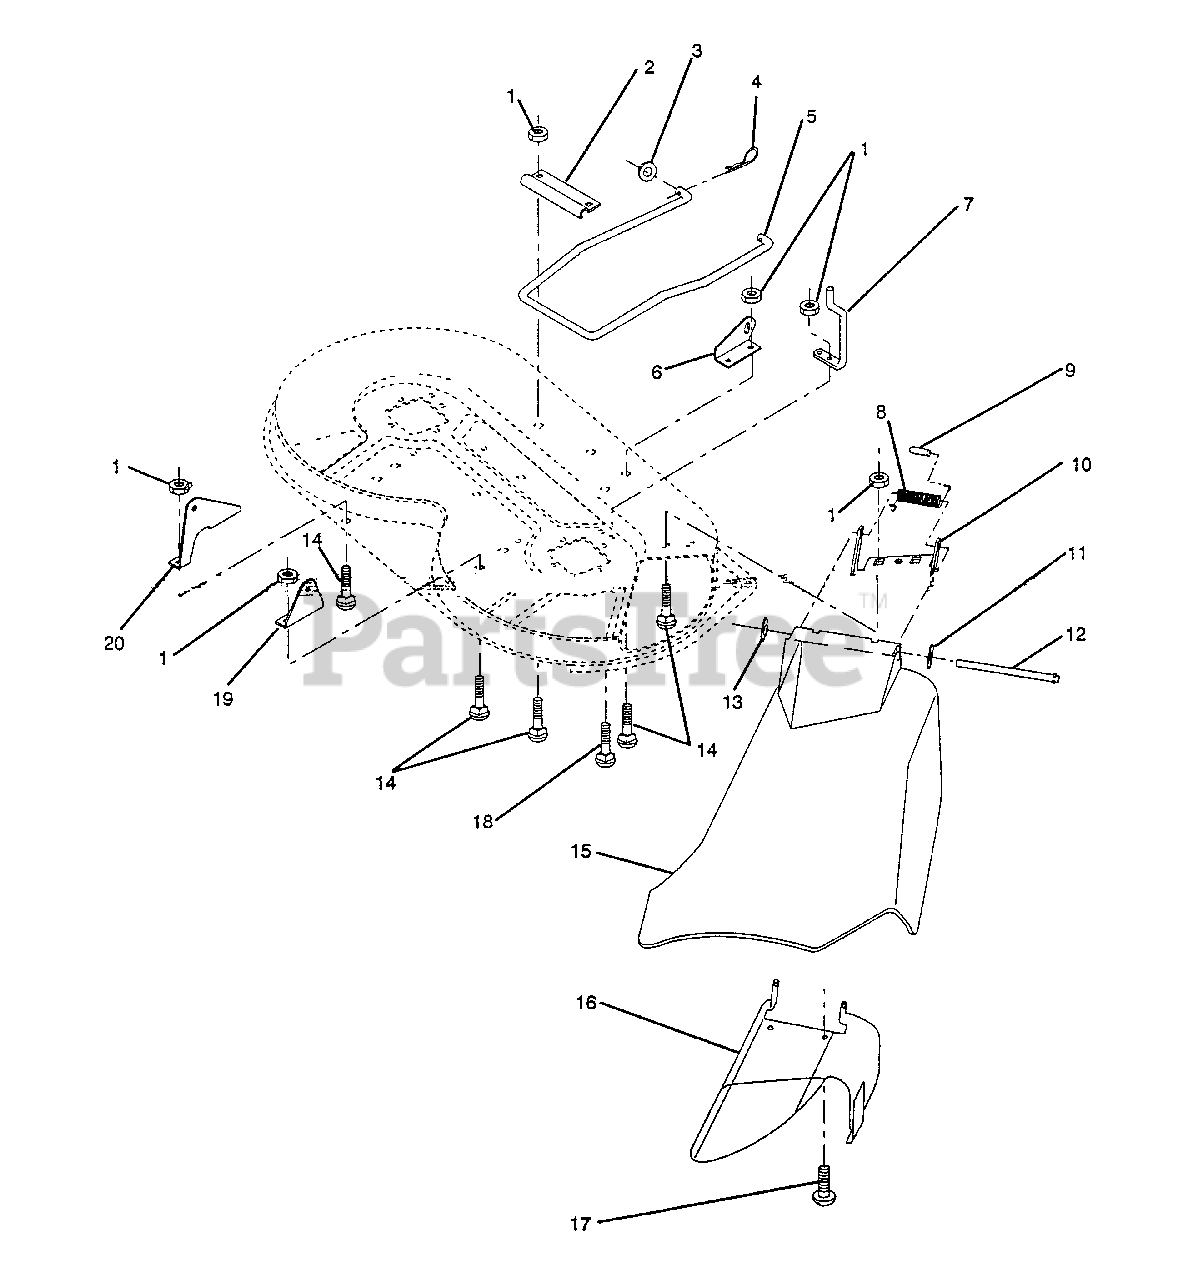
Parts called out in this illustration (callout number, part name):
1	Nut Crownlock 5/16-18
2	Bracket, Stabilizer Link
3	Washer 17/32 x 1-1/16 x 13 Ga.
4	Retainer, Spring
5	Stabilizer, Mower Link
6	Bracket, R.H. Front Lift
7	Guide, Front Mandrel R.H. Mower Belt
8	Spring, Torsion
9	Cap, Sleeve
10	Bracket, Deflector
11	Washer 11/32 x 5/8 x 16 Ga.
12	Rod, Hinge
14	Bolt, Carriage 5/16-18 UNC x 5/8
15	Guard, Discharge
16	Assembly, Deflector Support
17	Screw, Pan Hd. PLT-30
18	Bolt, Hex Head 5/16-18 UNC x 3/4
19	Bracket, R.H. Rear Lift
20	Bracket, L.H. Rear Lift
